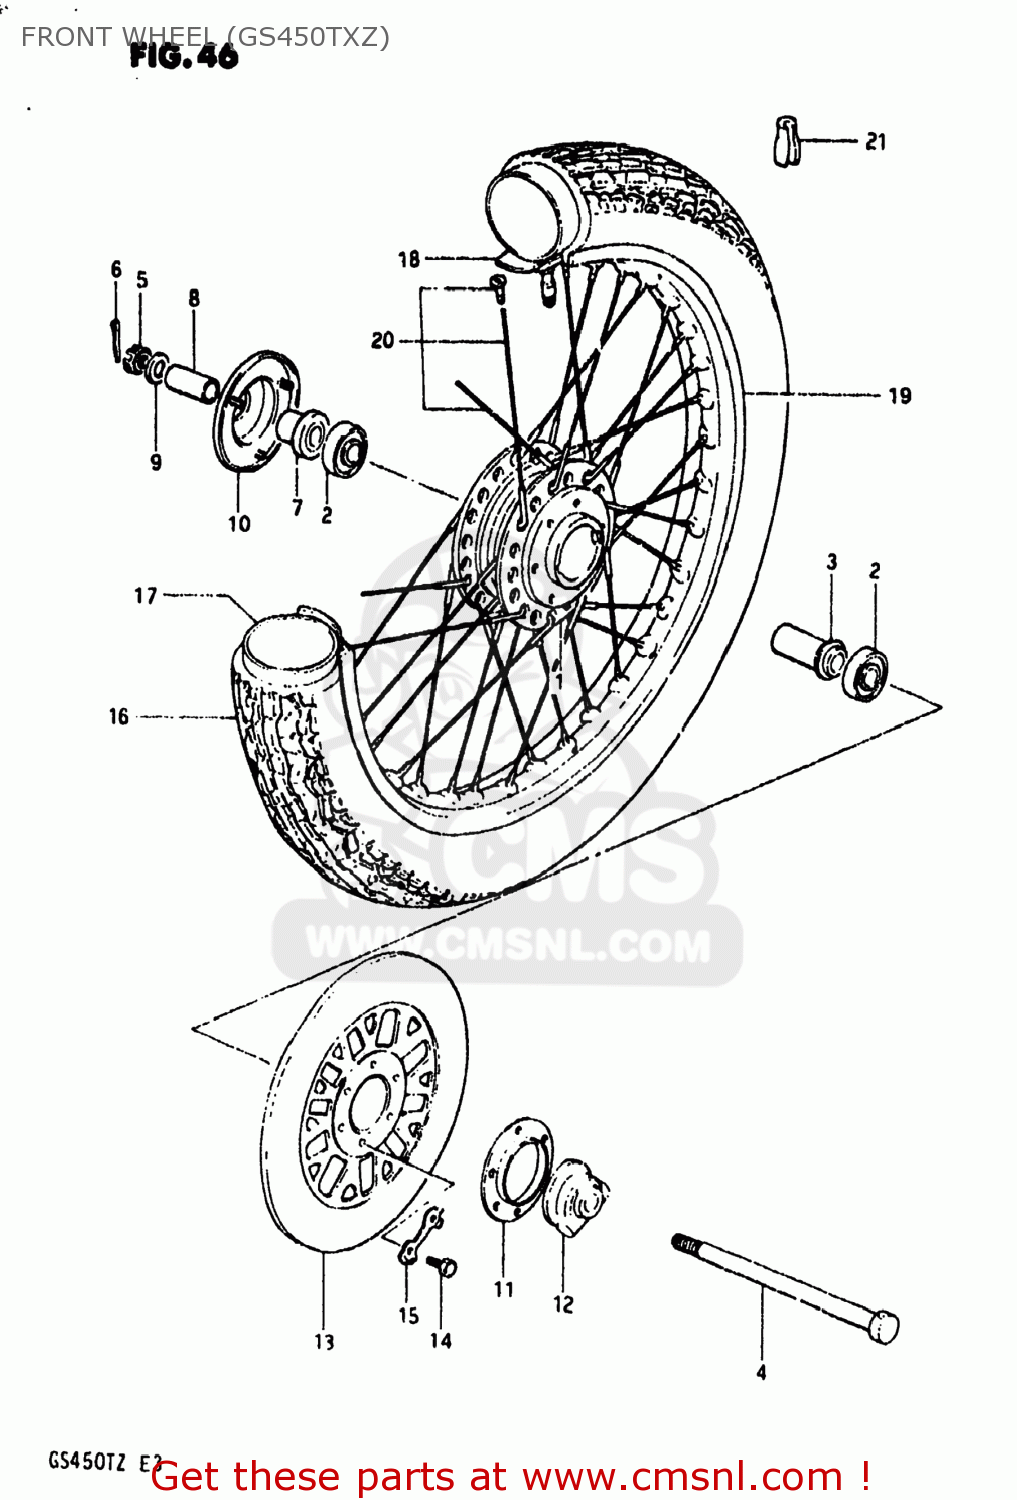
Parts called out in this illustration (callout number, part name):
1	DRUM,FRONT HUB
2	BEARING
3	SPACER,FR HUB BEARING
4	AXLE,FRONT
5	NUT 12MM
6	COTTER PIN
7	SPACER,FR HUB BEARING,R
8	SPACER(15X22X30)
9	WASHER
10	COVER,FR HUB,R
11	DUST SEAL,SPEEDOMETER GEAR BOX
12	BOX ASSEMBLY,SPEEDOMETER GEAR
13	DISC,FR BRAKE
14	BOLT(8X25)
15	WASHER
16	TIRE
17	TUBE 2.75-19 070-483MM
18	PROTECTOR,WHL INR TUBE
19	RIM,FR WHEEL
20	SPOKE ASSY,FR
21	BALANCER,WHEEL (B)
